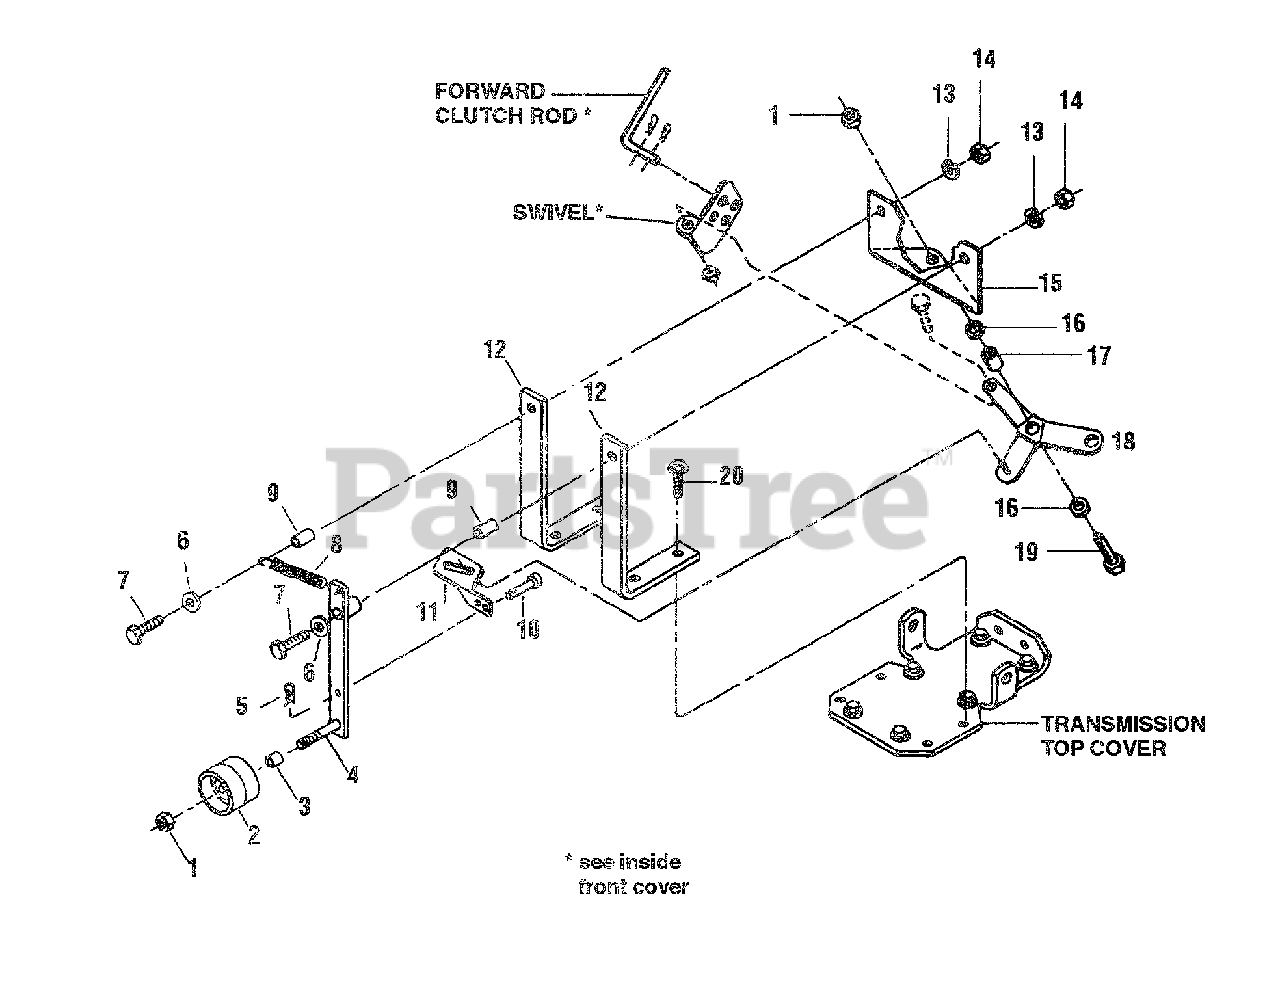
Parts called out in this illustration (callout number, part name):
1	Locknut-hex, 3/8-16
2	Pulley-idler, forward tiller
3	Spacer
4	Idler Arm-left, forward tiller direction
5	Hairpin Cotter
6	Washer-plain, 5/16
7	Screw-hex hd., 5/16-18 x 2-1/4
8	Spring
9	Pivot Bushing
10	Pin
11	Forward Link
12	Mounting Bar
13	Lockwasher-5/16
14	Nut-hex, 5/16-18
15	Shifting Base
16	Spacer-Bushing
17	Bushing-bellcrank
18	Bellcrank
19	Screw-hex hd., 3/8-16 x 1-1/4
20	Screw-flanged hex hd., 5/16-18 x 1
